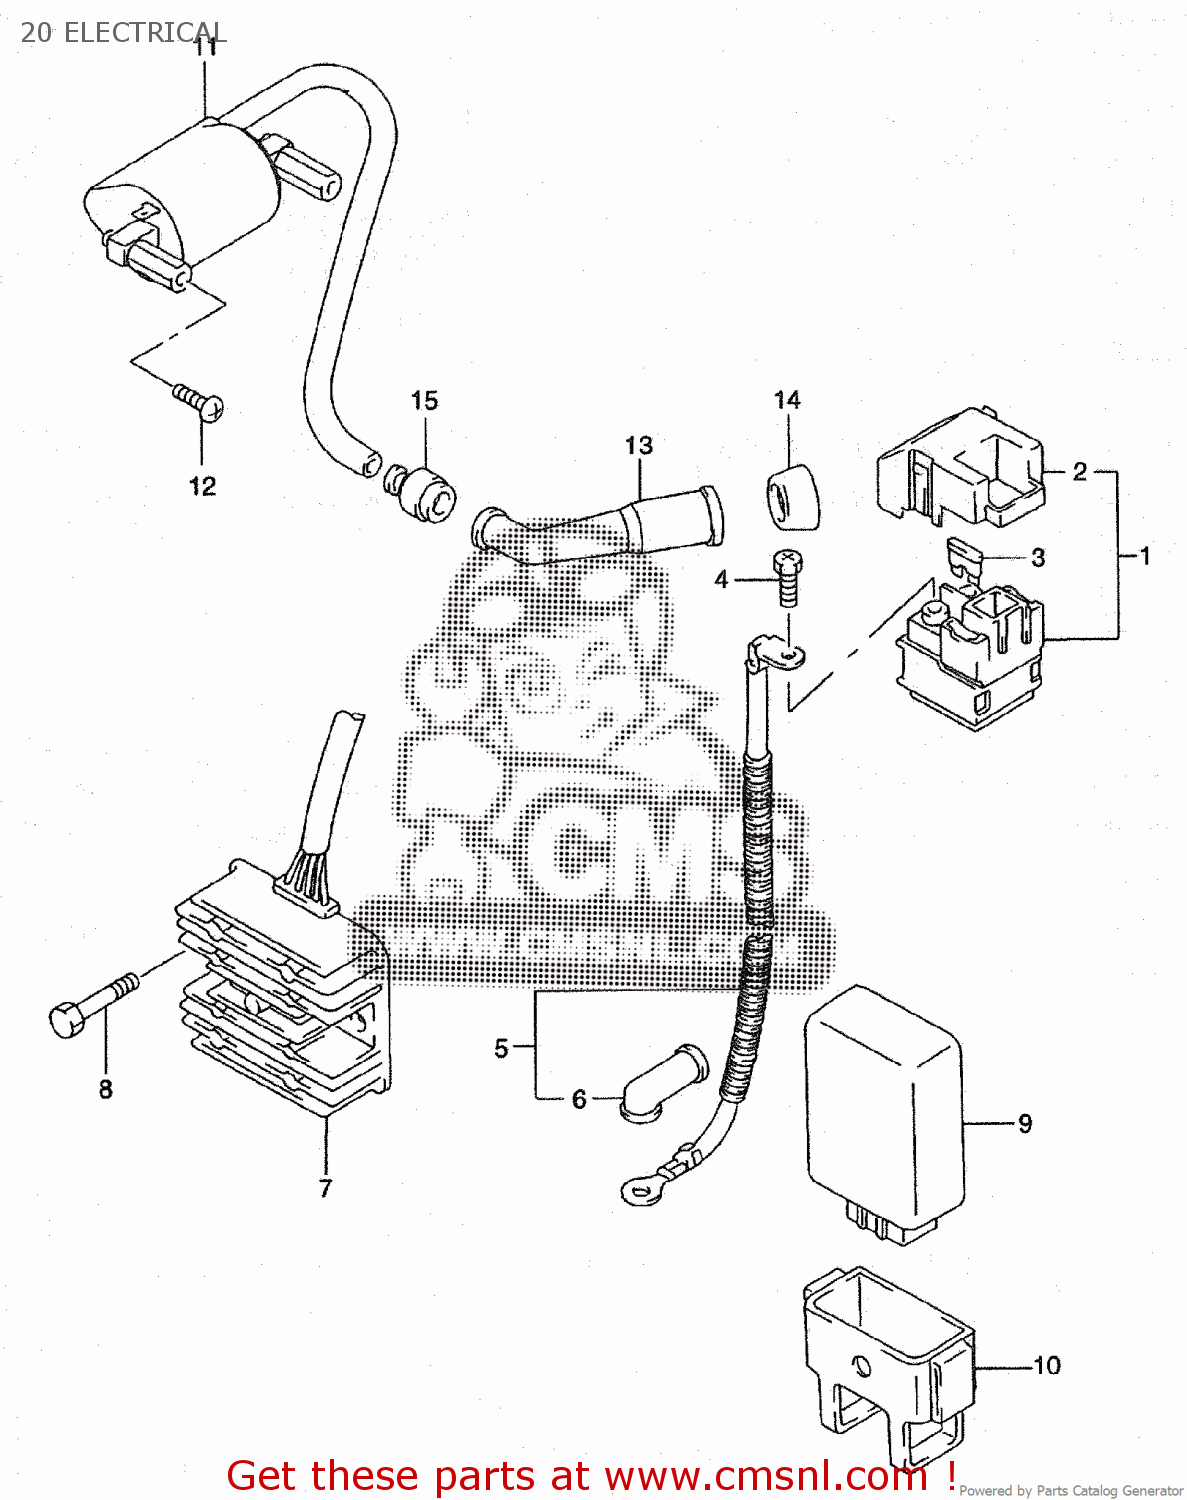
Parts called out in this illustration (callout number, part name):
1	RELAY ASSY,STARTING MOTOR
2	COVER
3	FUSE(20A)
4	SCREW(6X8)
5	WIRE,STARTER MOTOR LEAD
6	CAP,STARTER MOTOR LEAD
7	RECTIFIER ASSY
8	BOLT,OIL FILLE
9	IGNITOR ASSY
11	COIL ASSY,IGNITION
12	SCREW 5X12
13	CAP ASSY,SPARK PLUG
14	SEAL,SPARK PLUG CAP
15	SEAL,HIGH TENSION CORD
